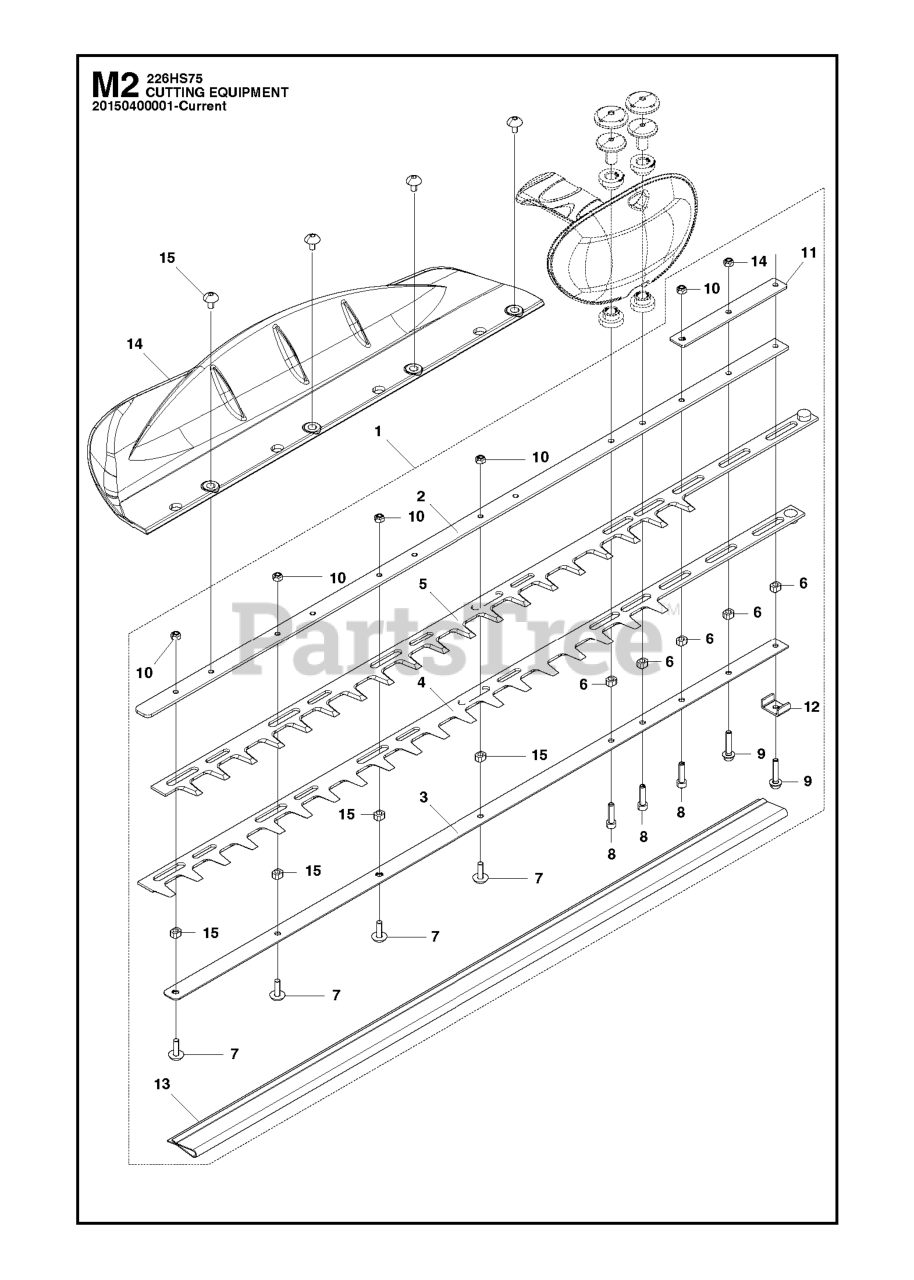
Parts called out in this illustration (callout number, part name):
2	PLATE UPPER
3	PLATE LOWER
8	BOLT
